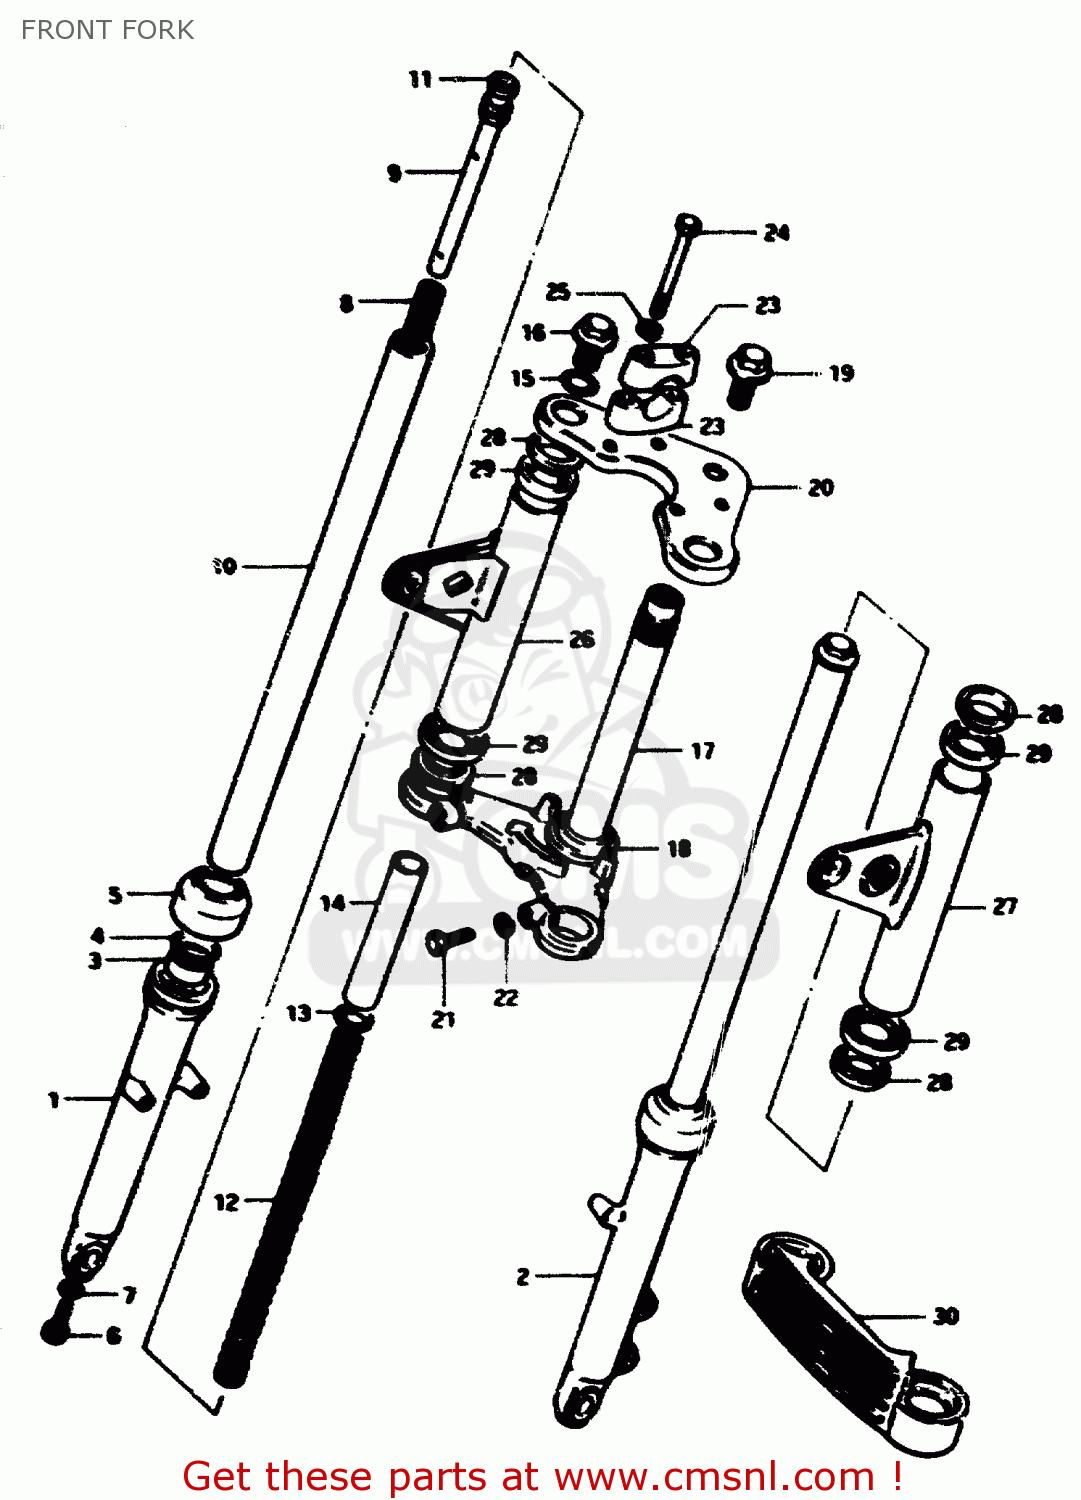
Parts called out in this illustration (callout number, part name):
1	OUTER TUBE, RH
2	OUTER TUBE, LH
3	SEAL,OIL
4	RING,OIL SEAL STOPPER
5	DUST SEAL
6	BOLT(8X27)
7	GASKET (NAS)
8	SPRING,REBOUND
9	CYLINDER
10	INNER TUBE
11	RING,PISTON
12	SPRING
13	JOINT,SPRING
14	SPACER,SPRING
15	O-RING,FORK INNER TUBE
16	CAP
17	STEERING STEM
18	RACE,STEERING OUTER LWR
19	BOLT
20	STEM HEAD, STEERING
21	BOLT 10X30
22	LOCK WASHER
23	HOLDER,HANDLEBAR
24	BOLT 8X55
25	LOCK WASHER
26	BRACKET,HEADLAMP,RIGHT
27	BRACKET,HEADLAMP,LEFT
28	CUSHION
29	GUIDE, COVER
30	COVER
